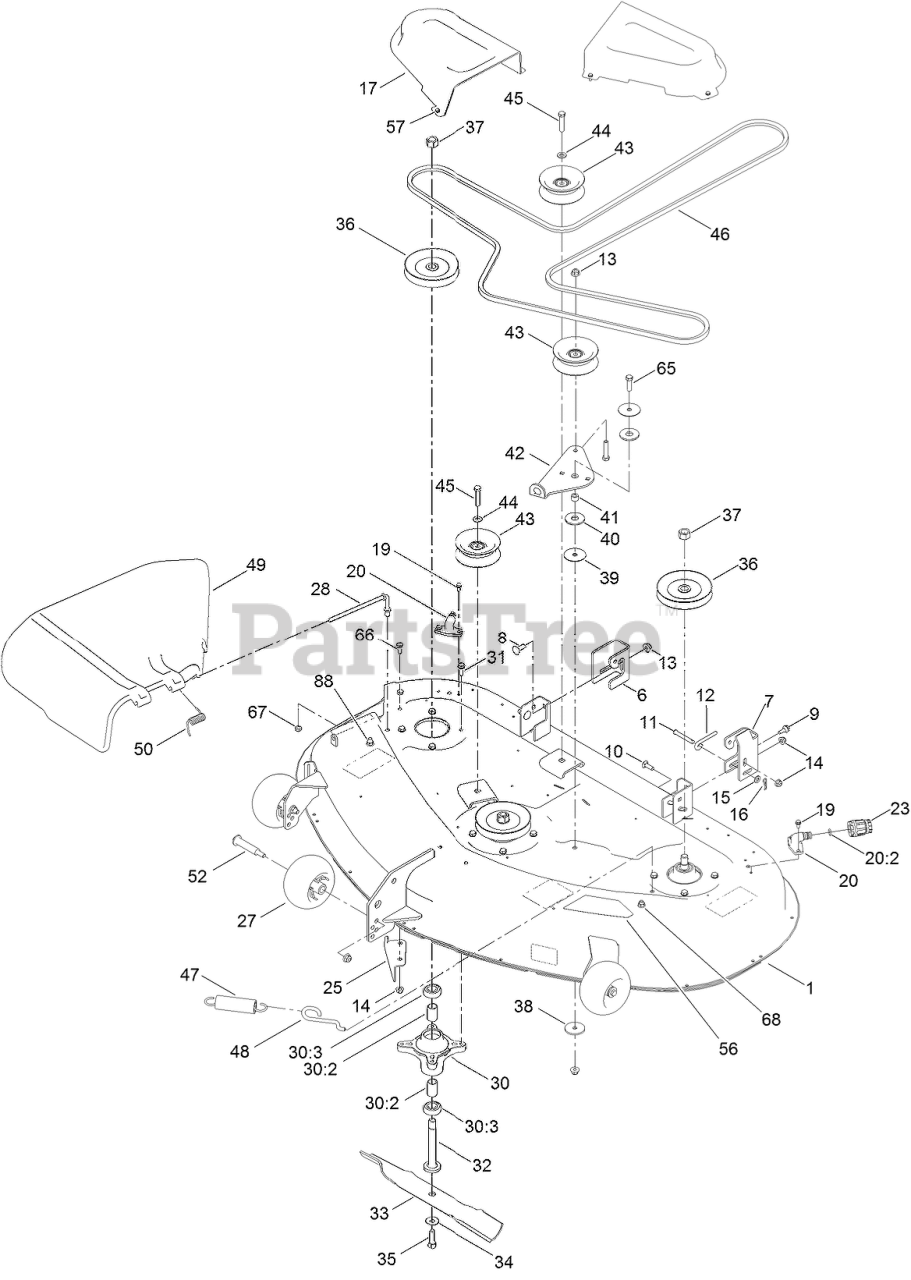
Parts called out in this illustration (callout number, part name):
1	50 INCH DECK AND DECAL ASM
6	BRACKET-HANGER, RH
7	BRACKET-HANGER, LH
8	BOLT-CARR
9	SCREW-SHOULDER,HWH
10	SCREW-CARR
11	PIN-CLEVIS
12	ROD-LEVEL, DECK
13	NUT-HF, NI
14	NUT-HF, NI
15	WASHER-PLAIN
16	PIN-COTTER
17	COVER-BELT
19	SCREW-HWH
20	FITTING-WASHOUT
20:2	O-RING
23	CONNECTOR-HOSE
25	BAFFLE-CUTOFF
27	ROLLER-SCALP, ANTI
28	ROD-PIVOT
30	SPINDLE ASM
30:2	SPACER
30:3	BEARING-BALL
31	SCREW-TAPTITE
32	SHAFT-SPINDLE
33	BLADE-HI LIFT
34	WASHER-BELLEVILLE
35	SCREW-HH
36	PULLEY
37	NUT-HEX
38	WASHER-REBOUND
39	WASHER
40	WASHER-FRICTION, COMPOSITE
41	SPACER
42	ARM-IDLER
43	PULLEY-IDLER, FLAT
44	WASHER-FLAT
45	SCREW-HH
46	V-BELT
47	SPRING-EXTENSION
48	HOOK-RETURN, SPRING
49	DEFLECTOR
50	SPRING-TORSION
52	BOLT-SHOULDER
57	SCREW-TAPTITE
65	SCREW-HH
66	SCREW-HH
68	SCREW-HH
88	SCREW-CARR
